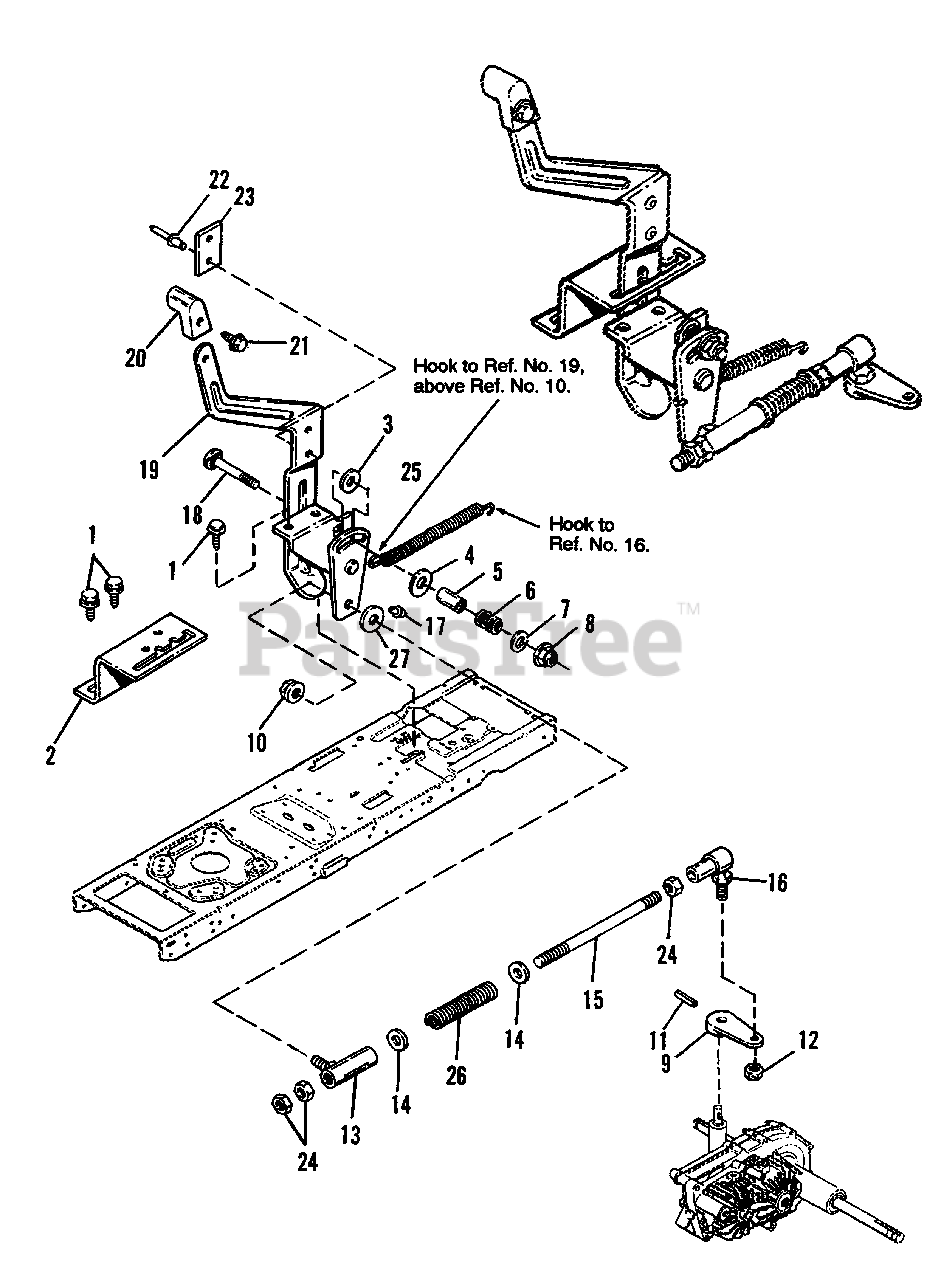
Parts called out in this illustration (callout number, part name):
1	SCREW, Taptite, 5/16-18 x 3/4
3	WASHER, 11/32 x 1-1/4 x 5/64
4	WASHER, 21/32 x 1-1/4 x 1/16
6	SPRING, Compression
7	WASHER, 11/32 x 1
8	NUT, Hex, Lock, Esna, 5/16-18
9	ARM CONTROL, Directional
10	NUT, Hex, Flange, Two way lock, 5/16-18
11	PIN, Spring, 5 mm x 45 mm
12	NUT, Centerlock 3/8-24
13	GUIDE ASSY, Rod
14	WASHER
15	ROD, Adjusting
16	BALL JOINT, R.H.
17	GREASE FITTING
18	CARRIAGE BOLT 5/16-18 x 2-1/4
19	SUPPORT ASSY., Control (Incl. Ref. Nos. 17, 22 & 23)
21	SCREW, Plastite, 1/4-20 x 1
22	RIVET, Tubular
23	PLATE, Wear
24	NUT, Jam, 3/8-24
27	WASHER, 1" O.D., .13 Thick
